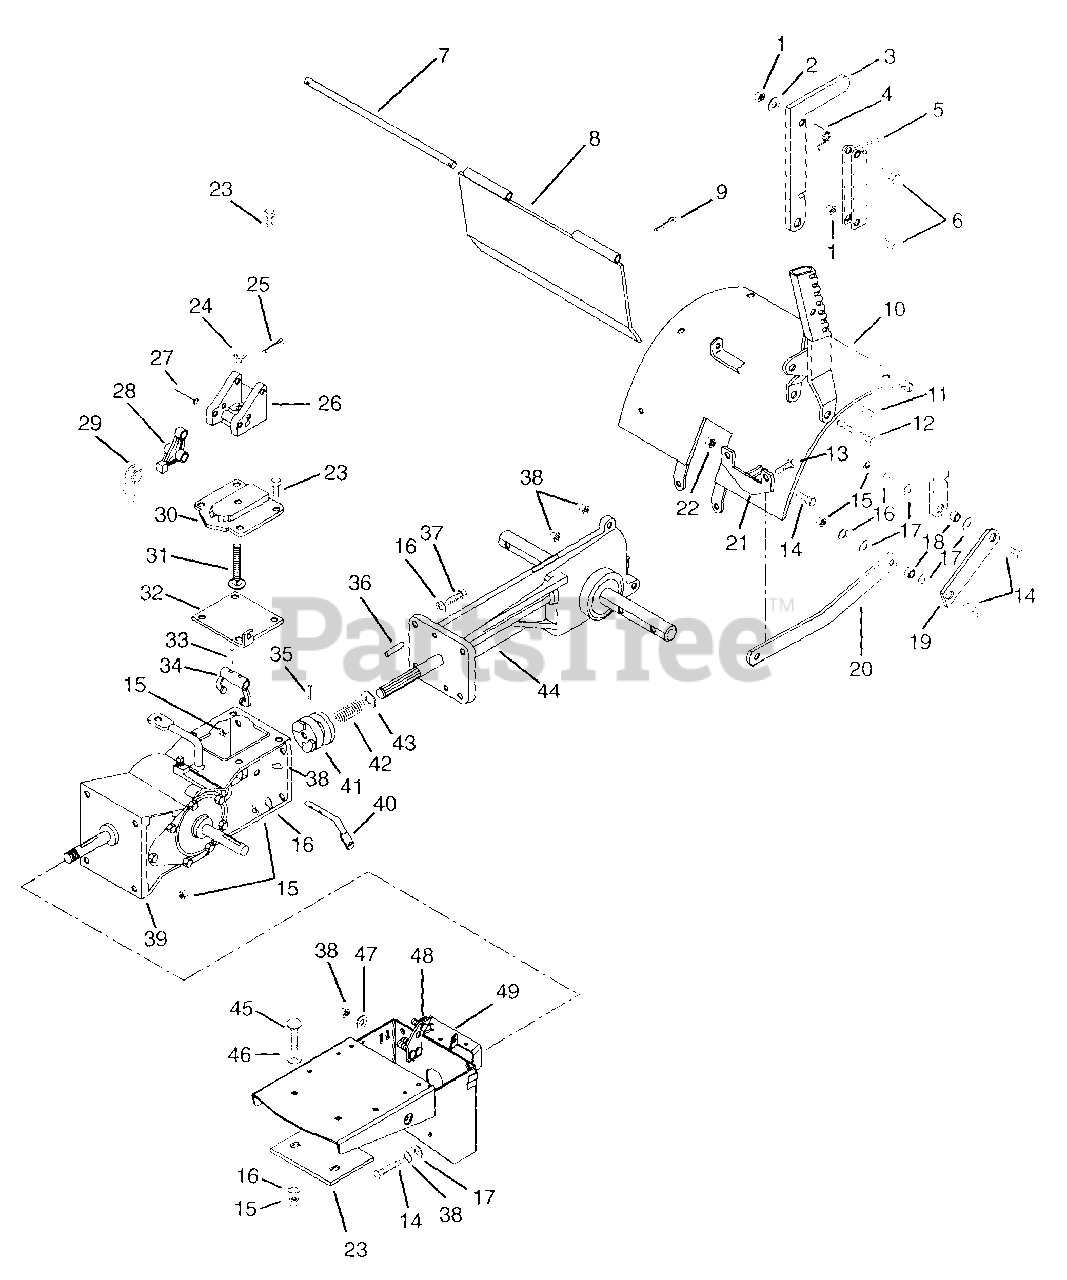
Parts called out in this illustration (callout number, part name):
1	@NUT-LK-CTR .25-20 YWZC
2	@WSHR-FL-STL.281X.62X.065 YWZC
3	HANDLE WELDMENT
4	SG-TORS .050X.25X2.33
5	TRIGGER
6	@BLT-HEX .25-20X1.25 GR5 YWZC
7	TAILBOARD PIN
8	TAIL BOARD WELDMENT
9	@PIN-CTR .09X.50 EXTPRSQCT YWZ
10	TINE HOOD W/DECAL
11	@BLT-HEX .31-18X1.25 GR5 YWZC
12	@BLT-HEX .31-18X3.50 GR5 YWZC
13	@BLT-HEX .38-16X2.25 GR5 YWZC
14	@BLT-HEX .38-16X1.25 GR5 YWZC
15	@NUT-HEX .38-16 YWZC
16	@WSHR-LK .38X.094 REG YWZC
17	@WSHR-FL-STL.406X.812X.065 YWZ
18	SPACER BUSHING .63 X .38 X .27
19	CHISEL POINT
20	DRAG LINK
21	PIVOT BRACKET
22	@NUT-LK-CTR .38-16 YWZC
23	WEIGHT, WAFER
24	NUT-SL .50-13
25	PIN-COTR .120X1.0 YWZC
26	HANDLEBAR BRACKET
27	PIN-ROLL .313X2.00
29	SG-TORS .109X.88X2.25
30	PIVOT CAP
31	SWIVEL BOLT
32	PIVOT BRACKET
33	PIN-ROLL .188X1.00
34	CLUTCH FORK
35	PIN-ROLL .125X1.00
36	PIN-GRV .375X1.00 TP C
37	@BLT-HEX .38-16X1.75 GR5 YWZC
38	@NUT-LK-CTR .31-18 YWZC
39	TRANSMISSION GEARCASE ASSY
40	TINE ENGAGING FORK SHAFT
41	TILLER JAW CLUTCH
42	SG-COMP .080X.97X2.18 WLD14
43	WSHR-FL-STL .755X1.375X.125
44	TILLER GEAR CASE - C.I.
45	BLT-RDHDSQNK .38-16X2.25 SHTPL
46	WSHR-FL-STL .630X1.005X.062 YZ
47	@WSHR-FL-STL.344X.688X.065YWZC
48	BELT FINGER BRACKET
